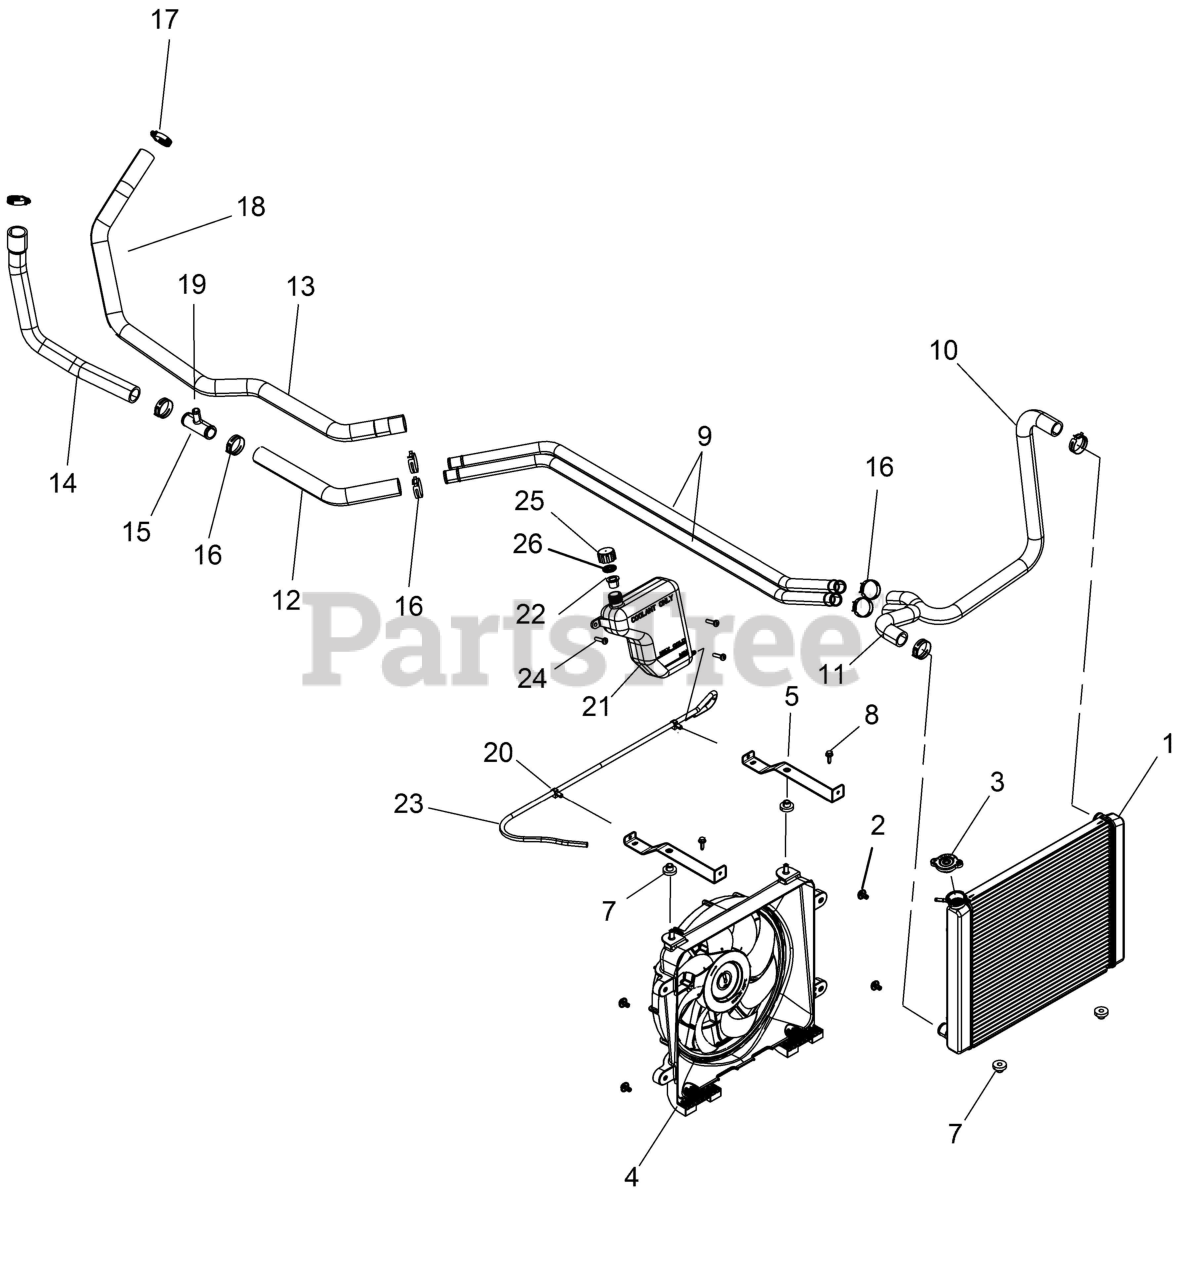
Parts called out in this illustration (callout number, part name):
1	ASM-RADIATOR,CORE
2	BOLT-M6X15MM
4	FAN-ASSEMBLY
5	MOUNT, RADIATOR, BLACK
8	SCR-M6X1.0X20,HXHD,FLG,TDFM,BL
9	TUBE, COOLANT, CREW, 1 IN
10	HOSE-UPPER,RAD
11	HOSE-LOWER,RAD
12	HOSE, ENGINE, IN
13	HOSE-ENG,OUTER
14	HOSE, ENGINE, BYPASS
15	CONNECTOR-TEE,1X1X0.5
16	CLAMP,SPRINGBAND 35/12,BLK
17	CLAMP-HOSE(WORM DR)25-40MM
18	CLIP-ROUTING
19	CLAMP-HOSE,SPRING,20MM
21	TANK-SURGE
22	CAP,PLUG9X(GRN),FLEX TEMP(10)
23	FUEL LINE-95 CENTIMETERS
24	SCR-#14X1 HI/LO-PH-PN TRX-M
25	CAP, OVERFLOW
26	GASKET (10)
